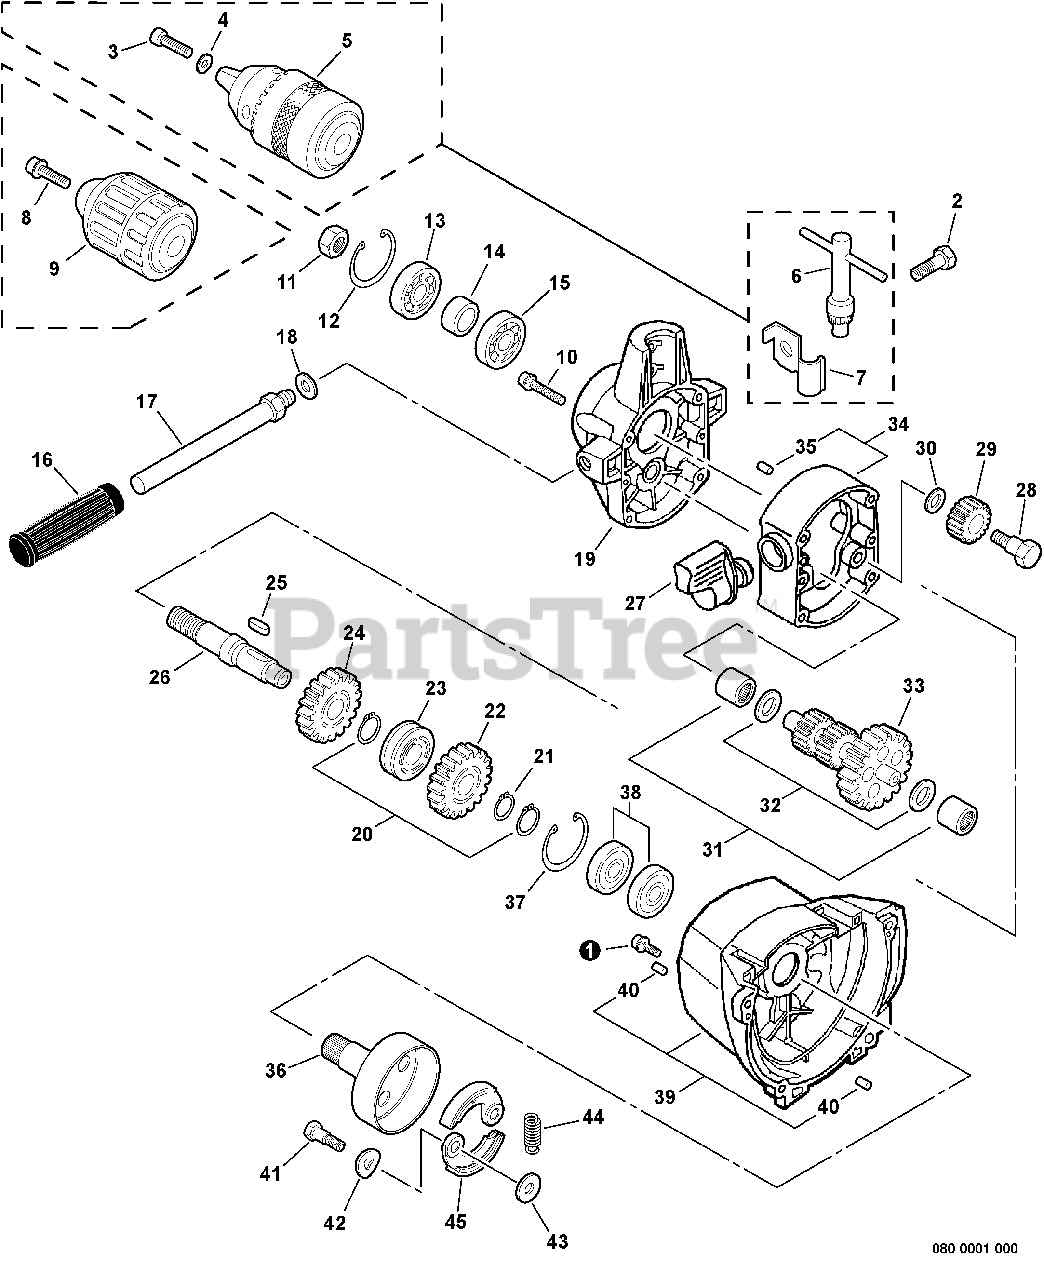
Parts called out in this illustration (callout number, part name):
1	SCREW - 5X18
2	BOLT - 10X15
3	SCREW - 6X20
4	WASHER - 6
5	CHUCK - KEYED
6	KEY, CHUCK
7	CLAMP, CHUCK KEY
8	BOLT - 6X20
9	CHUCK - KEYLESS
10	SCREW - 5X50
11	NUT - 12
12	RING, RETAINING - 32
13	BEARING, BALL - 6002
15	BEARING, BALL - 6002
16	GRIP, HANDLE
17	HANDLE - LEFT
18	WASHER - 10
19	CASE, GEAR
20	RING, RETAINING - 15
21	RING, RETAINING - 12
22	GEAR - SPUR
23	CAM, CLUTCH ADJUSTER
24	GEAR - SPUR
25	KEY - 4X16
26	GEAR - SHAFT
27	LEVER, CLUTCH
29	GEAR - SPUR
31	BEARING, NEEDLE
33	GEAR ASSY
34	GEAR CASE ASSY
35	PIN - LOCATING
36	DRUM, CLUTCH
37	RING, RETAINING - 32
38	BEARING, BALL - 6002D
39	FAN CASE ASSY
40	PIN - LOCATING
41	BOLT, CLUTCH
42	WASHER - SPRING
43	WASHER - 6
44	SPRING, CLUTCH
45	SHOE, CLUTCH
